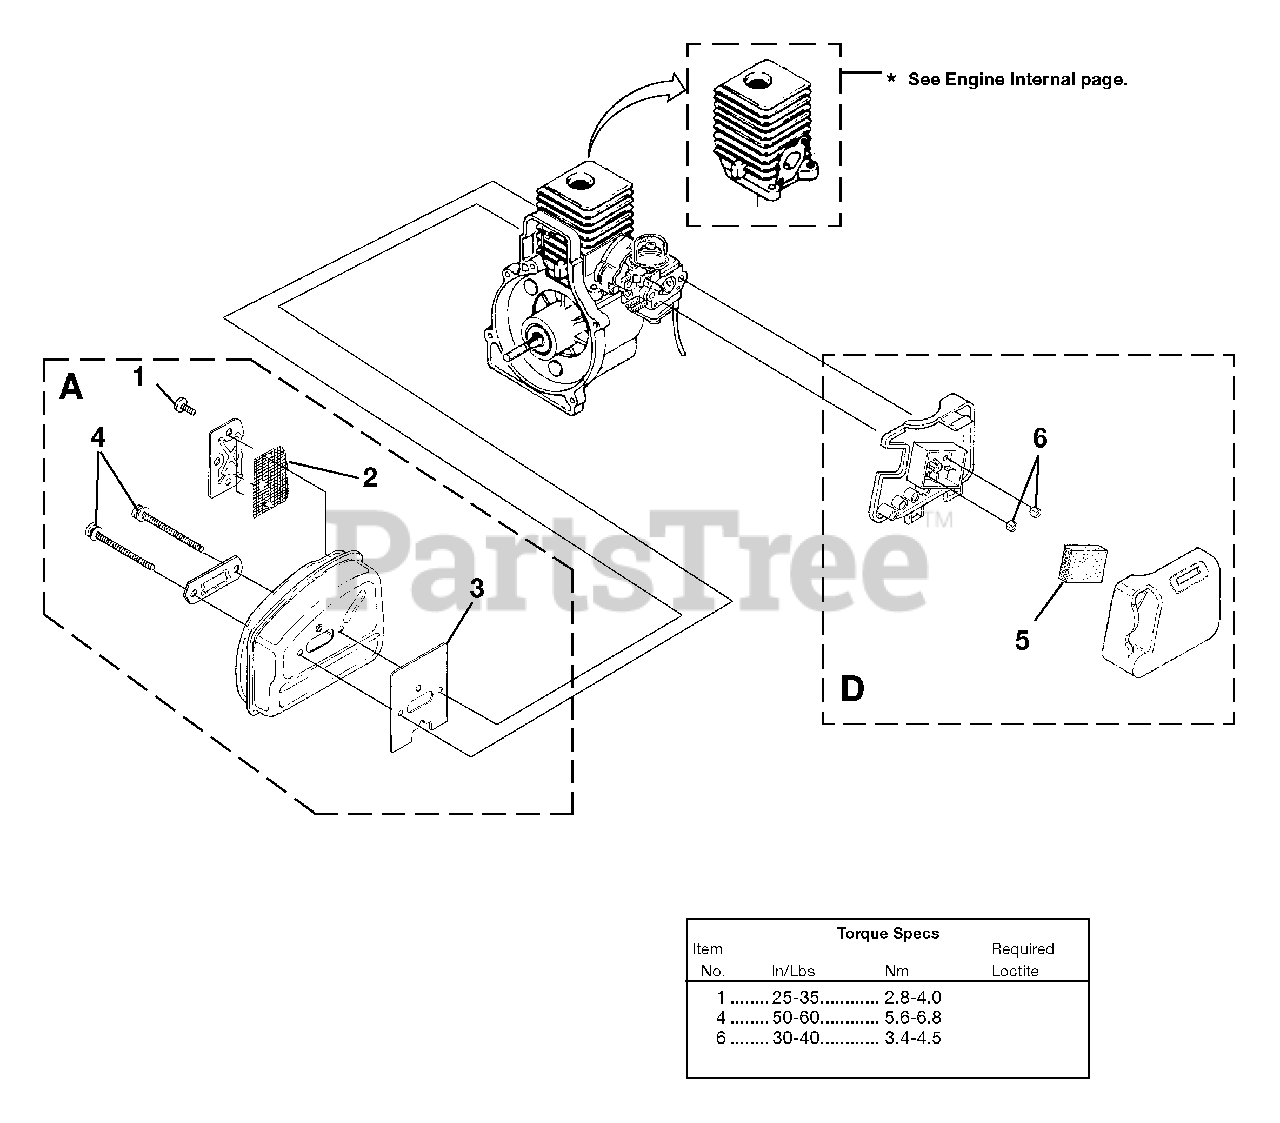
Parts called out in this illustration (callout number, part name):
1	SCREW, Taptite- (8-32 X 3/8")
2	SCREEN-Spark
3	GASKET-Muffler
4	SCREW, Truss Hd. - (10-24 X 2.188)
5	FILTER-AIR
6	NUT-Hex (10-24)
A	MUFFLER ASSY. (UT20811 & B & D)
D	AIR FILTER KIT
